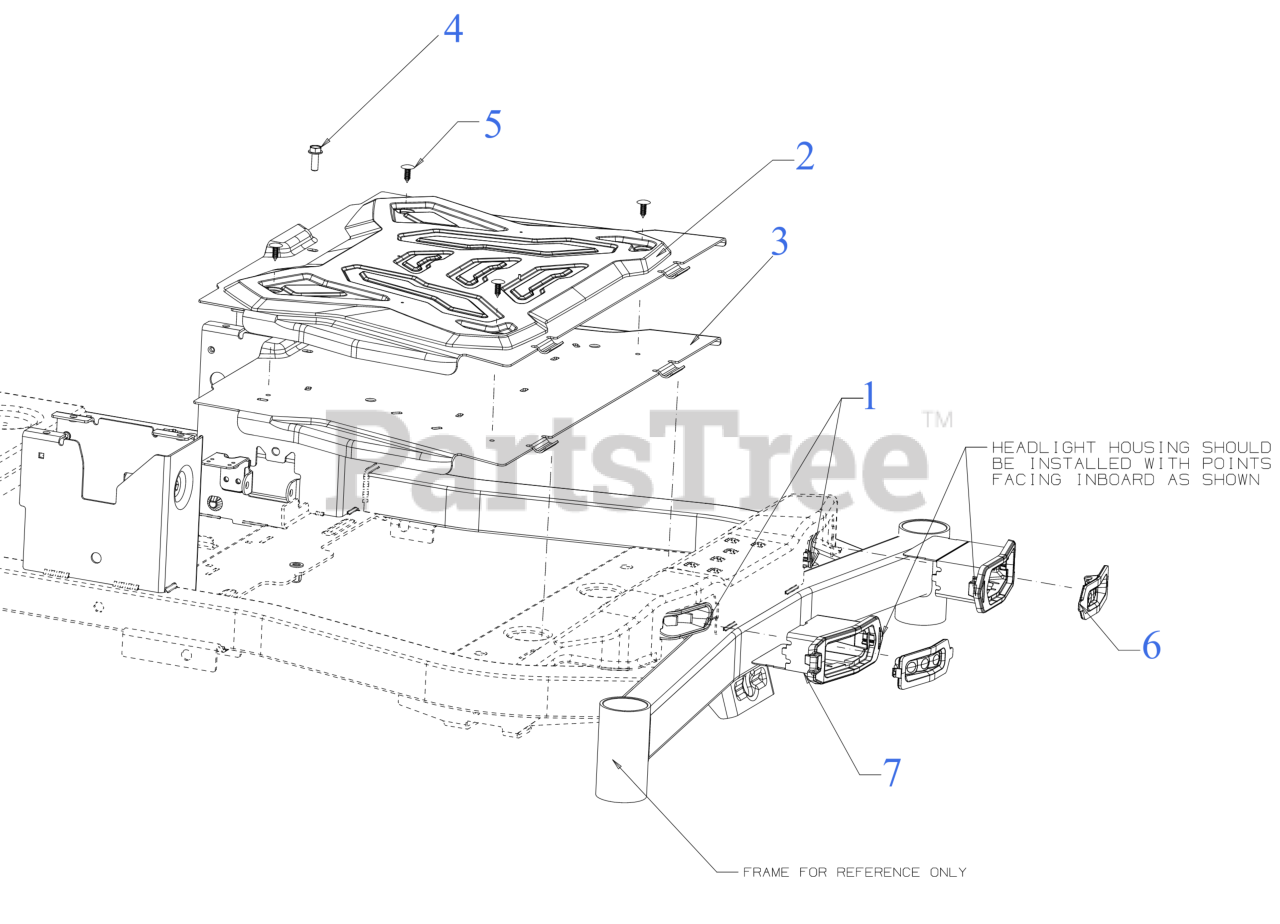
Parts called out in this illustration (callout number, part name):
1	HEADLIGHT HARNESS (W/LED)
3	FLOORBOARD
4	SCREW 5/16-18 x .875 GR5
5	RATCHET CLIP .250
6	LED HEADLIGHT LENS
7	LED HEADLIGHT HOUSING
